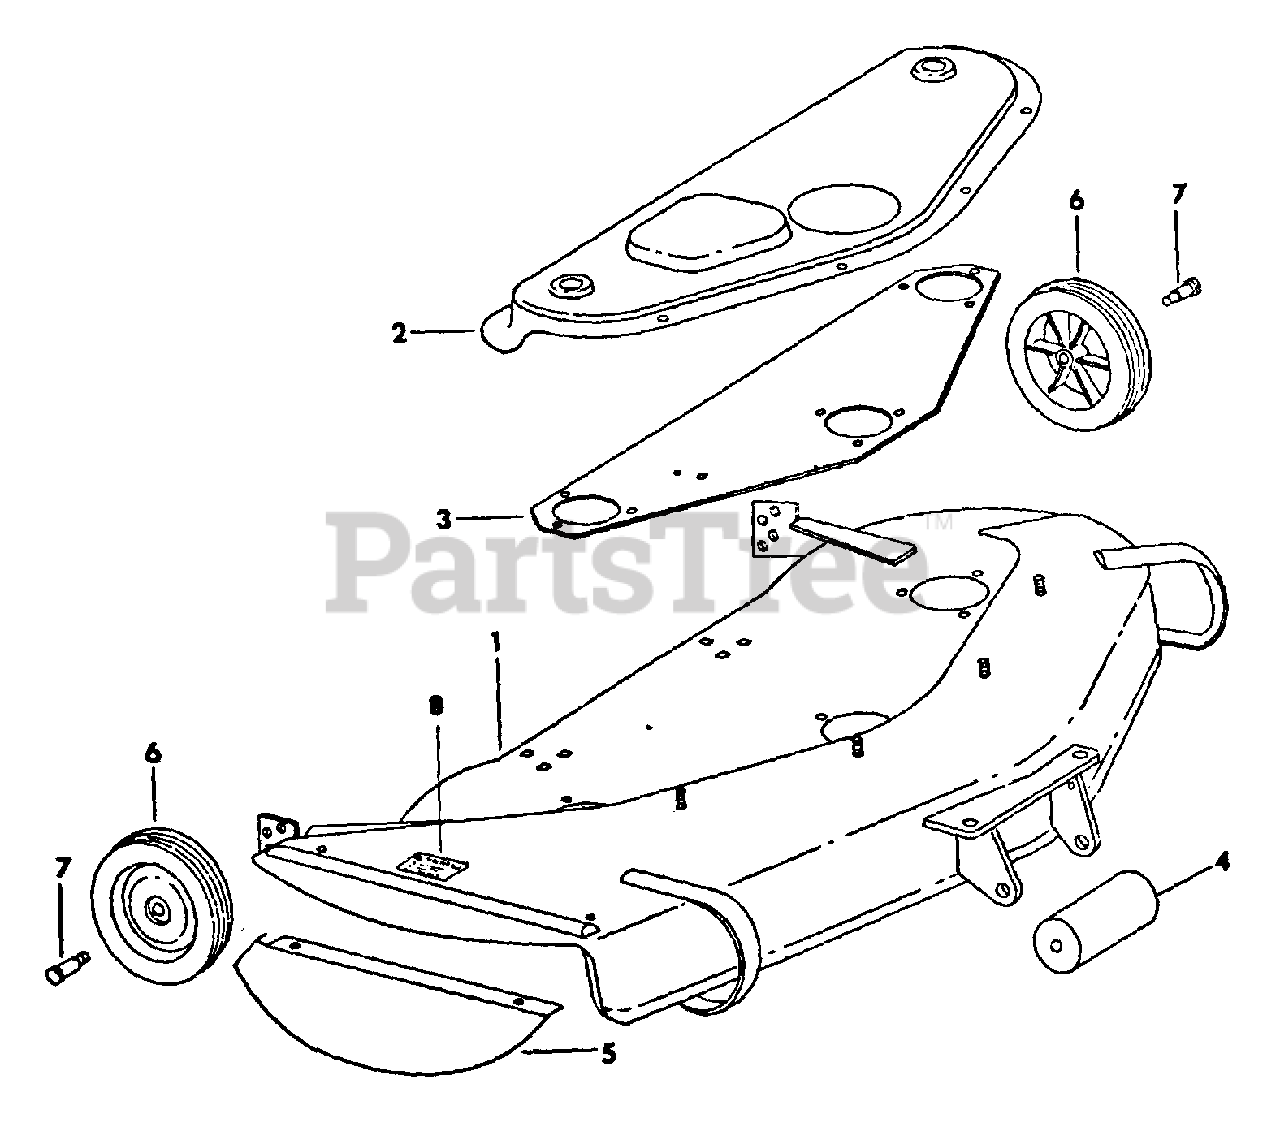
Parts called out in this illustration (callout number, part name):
1	HOUSING w/PRODUCT GRAPHIC 57801-C2
2	COVER, MOWER BELT
3	PLATE, SPINDLE MTG
4	ROLLER, FRONT
5	SHIELD, DEFLECTOR REPLACES 59676-C1
6	WHEEL, 7 IN. GAUGE
7	BOLT, SHOULDER
8	PRODUCT GRAPHIC, CAUTION
